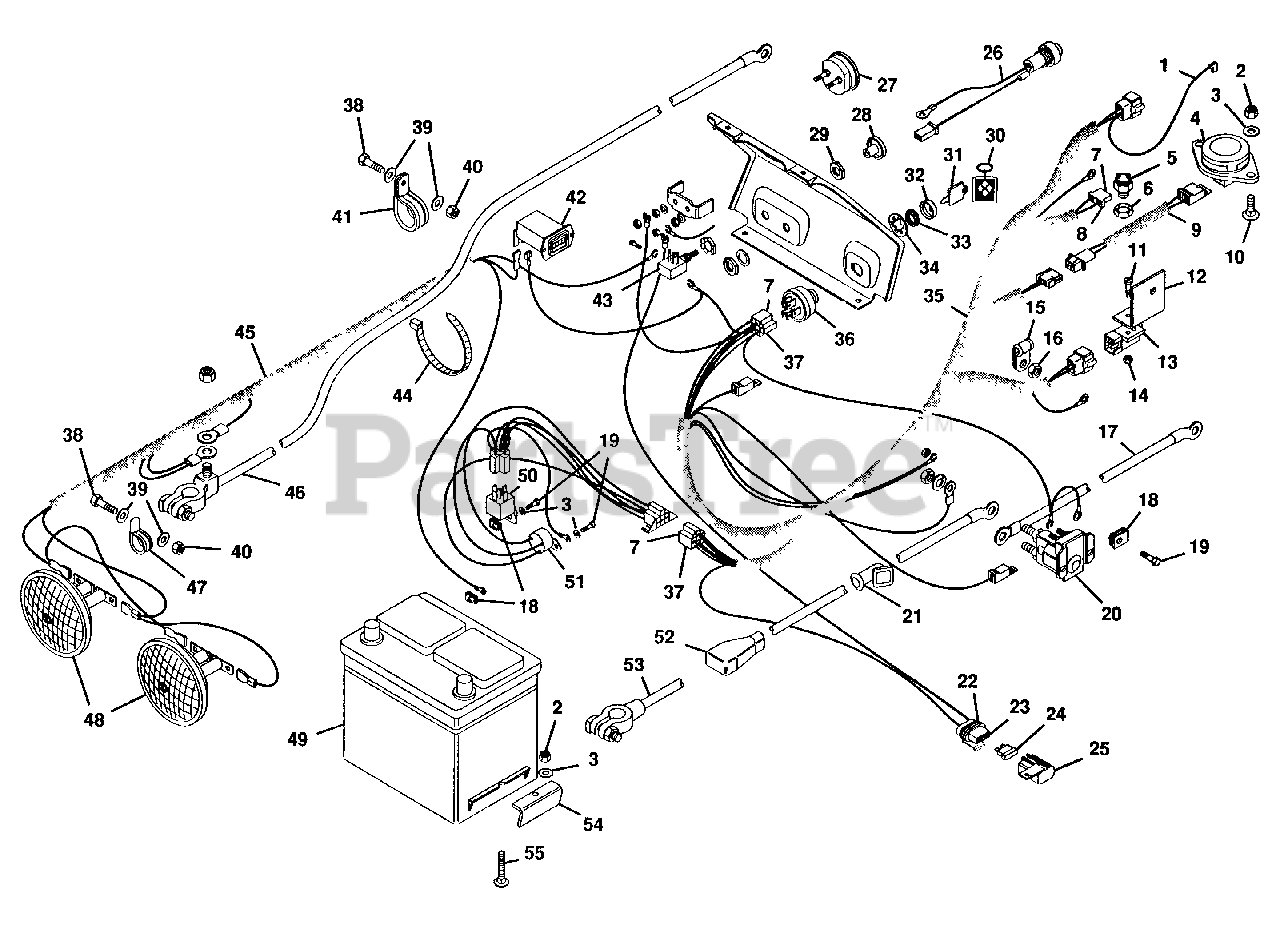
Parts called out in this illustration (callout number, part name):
1	WIRE
2	NUT, LOCK 1/4-20
3	WASHER, FLAT .281X.625X.065
4	SWITCH, SEAT
5	SWITCH, INTERLOCK
6	NUT, STAMPED 9/16-18
7	TERMINAL
8	CONNECTOR, 2-WIRE SWITCH
9	HARNESS, WIRING SEAT SWITCH
10	BOLT, 1/4-20X.75 RD HD SQ NK
11	SCREW, MACHINE 10-24X.75 PHD
12	BRACKET, PTO SWITCH
13	SWITCH, INTERLOCK
14	NUT, LOCK 10-24
15	CLAMP
16	NUT, LOCK 3/8-16
17	CABLE, STARTER
18	NUT, SPEED 1/4-20
19	BOLT, HEX 1/4-20X.75
20	SWITCH, MAGNETIC
21	BOOT, BATTERY CABLE
22	CONNECTOR
23	TERMINAL, 14-16 GAUGE
24	FUSE, 25 AMP
25	COVER
26	LIGHT, INDICATOR
27	GAUGE, AMMETER
28	KNOB, LIGHT SWITCH
29	NUT, SPECIAL LIGHT SWITCH
30	CHAIN, KEY
31	KEY, IGNITION SWITCH
32	BOOT, 9/16 SWITCH
33	NUT, JAM 9/16-24
34	WASHER, LOCK 9/16 INT. TOOTH
35	HARNESS, WIRING
36	SWITCH, IGNITION
37	CONNECTOR
38	BOLT, HEX 5/16-18X1.00
39	WASHER, FLAT .344X.688X.065
40	NUT, LOCK 5/16-18
41	CLAMP, STEEL 1.00
42	HOURMETER
43	SWITCH, LIGHT
44	TIE, CABLE
45	HARNESS, WIRING GROUND AND LIGHT
46	CABLE, NEGATIVE BATTERY
47	CLAMP, STEEL .625
48	HEADLIGHT
49	BATTERY, 12 VOLT
50	RELAY
51	MODULE, TIME DELAY
52	COVER, BATTERY TERMINAL
53	CABLE, BATTERY TO MAGNETIC SWITCH
54	CLAMP
55	BOLT, 1/4-20X2.00 RD HD SQ NK
